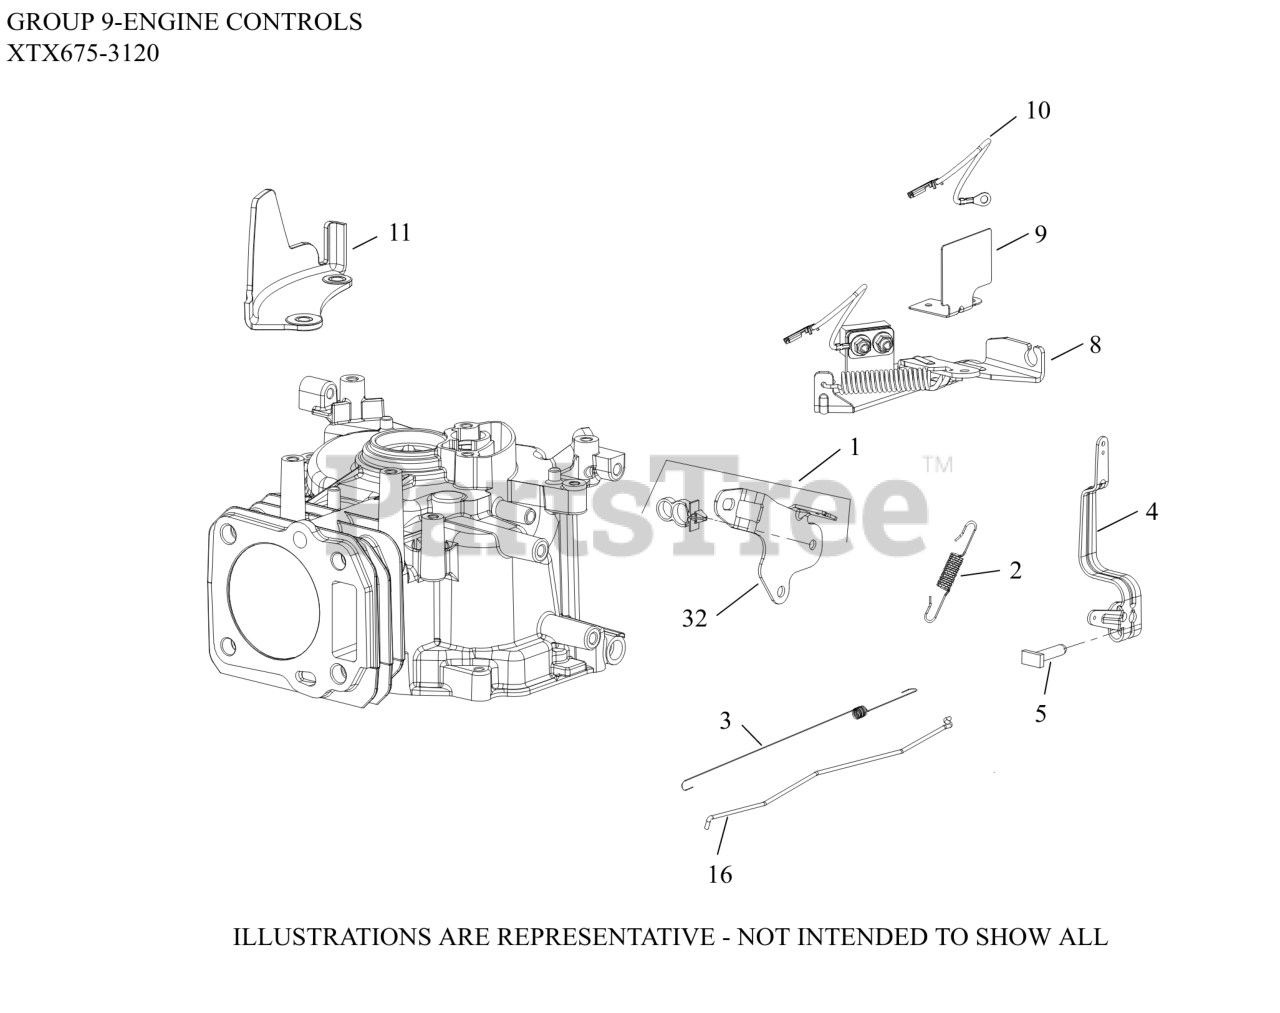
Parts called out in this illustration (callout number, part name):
1	BRACKET ASSEMBLY, FIXED SPEED CONTROL
2	SPRING, GOV (2800-3300 RPM)
3	SPRING, LINKAGE
5	SCREW, RECTANGLE HEAD (M6)
8	BRAKE ASSEMBLY
9	GUARD, BRAKE - USE 14 314 30-S
10	LEAD, KILL (BRAKE TO IGN. MODULE)
11	GUARD, FINGER
16	LINKAGE, GOVERNOR-(#1407927S)
32	BRACKET, FIXED SPPED - DISCONTINUED
34	LEVER, GOVERNOR
